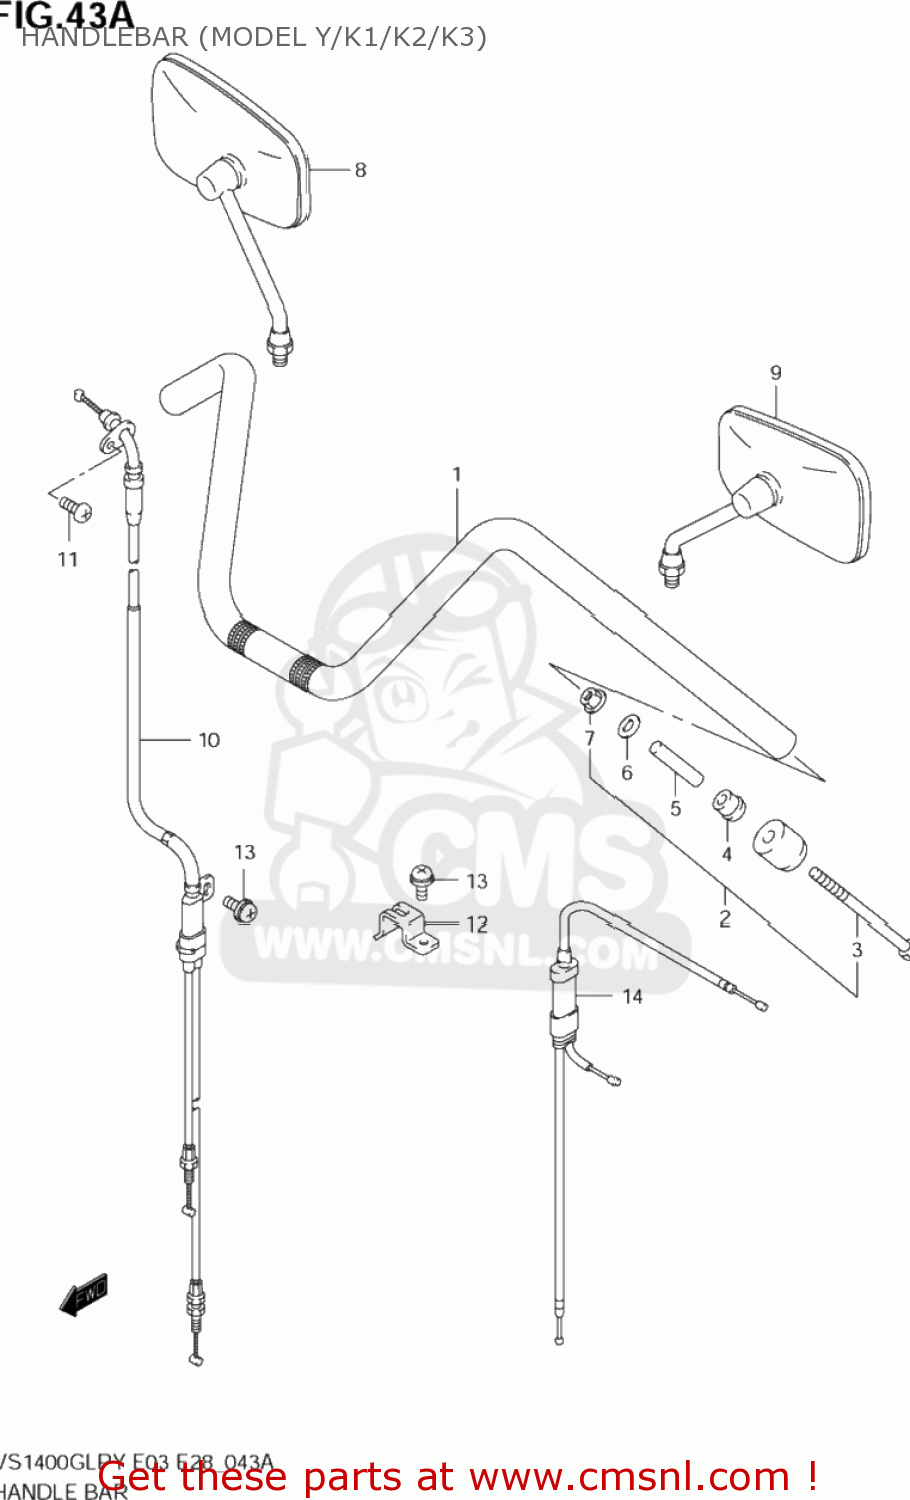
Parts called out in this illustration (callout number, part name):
1	HANDLEBAR
2	BALANCER SET,HANDLEBAR
3	SCREW(6X110)
4	EXPANDER,HANDLE BALANCER NO.2
5	SPACER,EXPANDER
6	WASHER(6.5X18X2)
7	NUT
8	MIRROR ASSY,RR VIEW,R
9	MIRROR ASSY,RR VIEW,L
10	CABLE ASSY,THROTTLE
11	SCREW
12	CLAMP,THROTTLE CABLE CONNECTOR
13	SCREW
14	CABLE ASSEMBLY,STARTER
